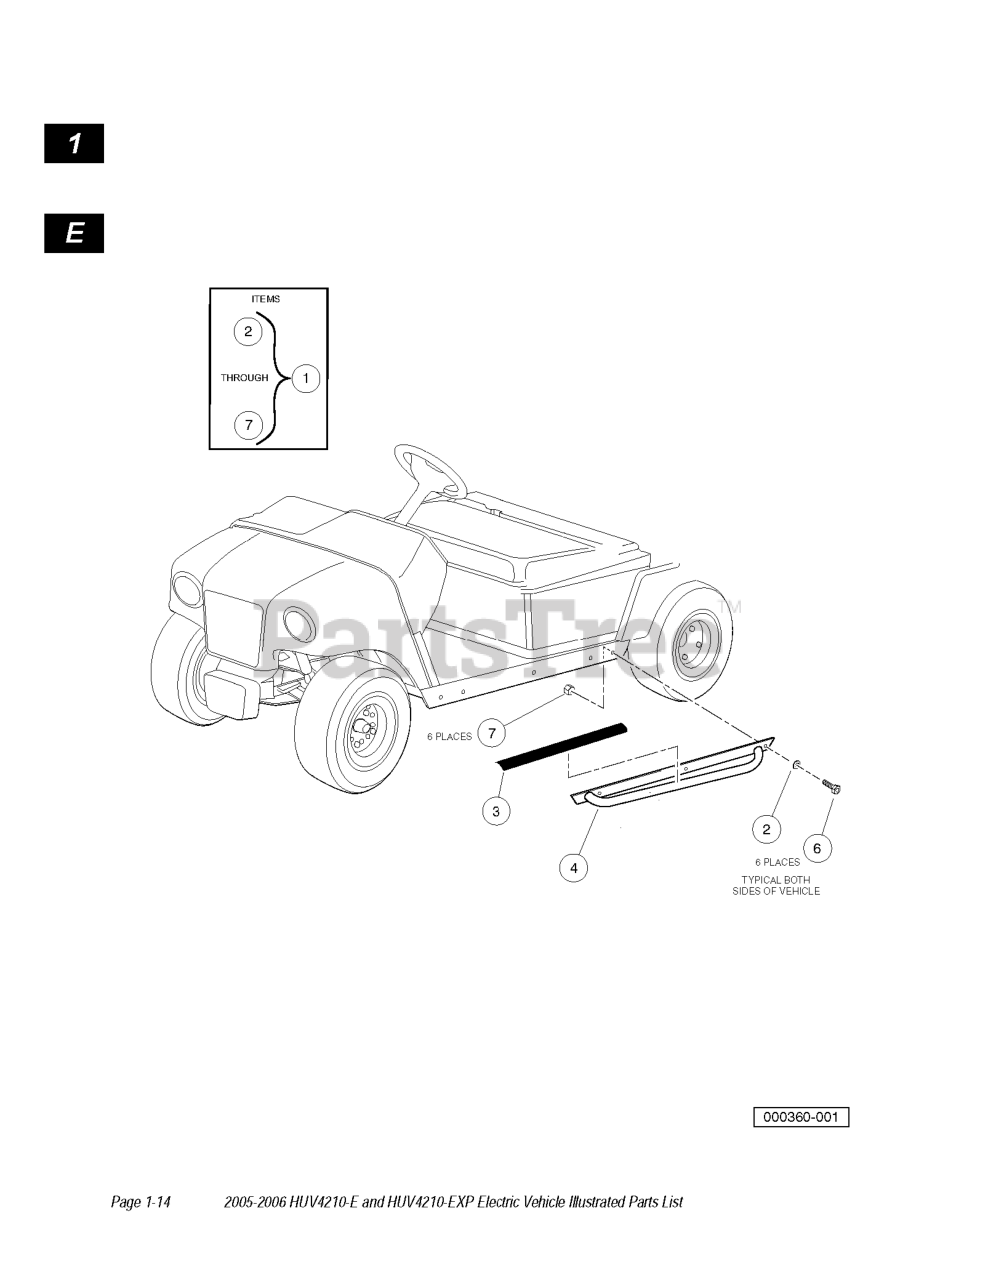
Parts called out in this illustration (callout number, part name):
1	Kit, Nerf Bar
2	WASHER, 3/8 FLAT
3	TAPE, NON-SKID, 26LG
4	Asm, Neff Bar, Driver (orange)
5	Asm, Neff Bar, Passenger (orange)
6	SCREW, CAP, HEX HD 3/8-16X1.00
7	LOCKNUT, 3/8-16 HEX
